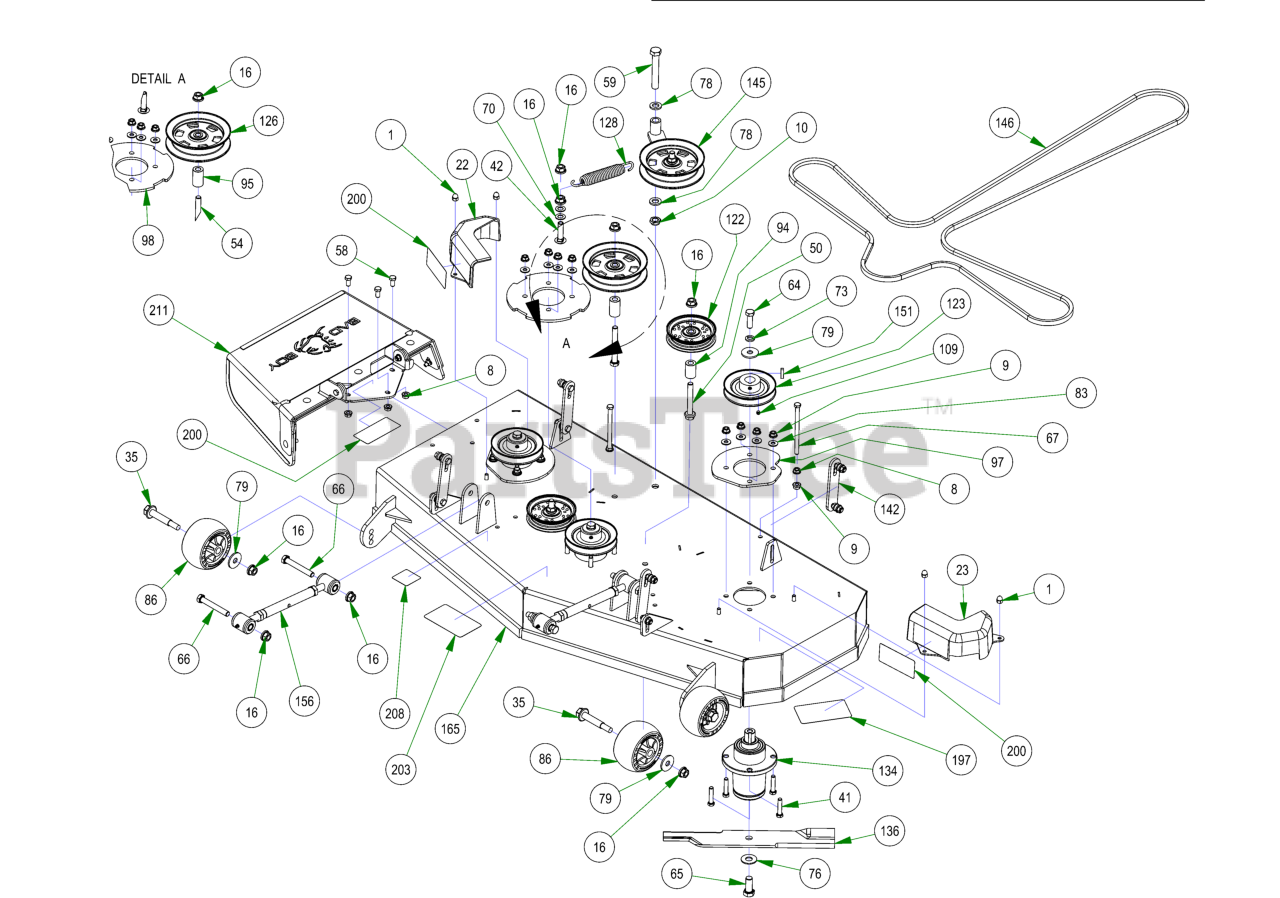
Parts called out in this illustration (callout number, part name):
1	5/16-18 ACORN NUT HIGH-CROWN ZC
8	3/8-16 HEX SERRATED FLANGE NUT HARD/ZINC
9	3/8-16 NYLON INSERT FLANGE LOCKNUT (GR.F) ZINC
10	5/8-11 NYLON INSERT JAM LOCKNUT ZINC
16	1/2-13 NYLON INSERT FLANGE LOCKNUT ZINC
22	pulley cover chute side
23	pulley cover non-chute side
35	Deck Wheel Bolt
41	3/8-16 X 1-3/4 HEX C/S (GR.5) ZC
42	1/2-13 X 2 CARRIAGE BOLT ZINC
50	1/2-13 X 3-1/2 HEX FLANGE BOLT (GR.8) ZINC
54	1/2-13 X 4 HEX CAP SCREW (GR.8) ZINC YELLOW
58	3/8-16 X 3/4 HEX CAP SCREW (GR.5) ZINC
59	5/8-11 X 4 HEX CAP SCREW (GR.8) ZINC YELLOW
64	1/2-20 X 1-1/2 HEX CAP SCREW (GR.5) ZINC
65	5/8-18 X 1-1/2 HEX CAP SCREW (GR.8) ZINC YELLOW
66	1/2-13 X 3-1/2 HEX CAP SCREW (GR.5) ZINC
67	3/8-16 X 5-1/2 HEX CAP SCREW (GR.5) ZINC
70	.517 SQ WDTH ID X .937 OD X .060 THICK F/W PHOS/OIL
73	1/2 SPLIT LOCKWASHER (GR.8) ZINC/YELLOW
76	5/8 USS FLAT WASHER (1-3/4" OD) GR.8 ZINC YELLOW
78	.635 ID X 1.120 OD X .140 THICK FLAT WASHER NYLON
79	1/2 BELLEVILLE WASHER (1-5/8 OD X .140 THK) ZINC
83	5/16 USS FLAT WASHER (7/8 OD) ZINC
86	Deck Wheel
94	.502 ID X .750 OD X 1.500 Long Spacer
95	1 3/4" Pulley Spacer
97	42&48 Deck Spindle Support Plate
98	Deck Spindle Support Plate
109	5/16-24 X 1/4 SOCKET SET SCREW (CUP PT) PLAIN
122	4 3/4 Idler Pulley - ABFI-76
123	5" Spindle Deck Pulley
126	5-3/4 Idler Pulley
128	Deck Idler Spring
134	Spindle Assembly
136	48" ZT/Mav/Compact Outlaw Blade with Fusion
142	Deck Hanger Assembly
145	2017 54"/48" Deck Idler Assembly
146	B147 Deck Belt
151	1/4 X 1 SQ MACHINERY KEY 1018 STL PLN
156	2018 Maverick Turnbuckle (Top Link)
165	2017 48" ZT Deck Welded Assembly
197	2018 48" Deck Decal
200	Danger Decal-Spindle/Discharge
203	Deck Belt Route Decal
208	Deck Impact Patent Decal 9591803
211	ZT Chute Assembly
